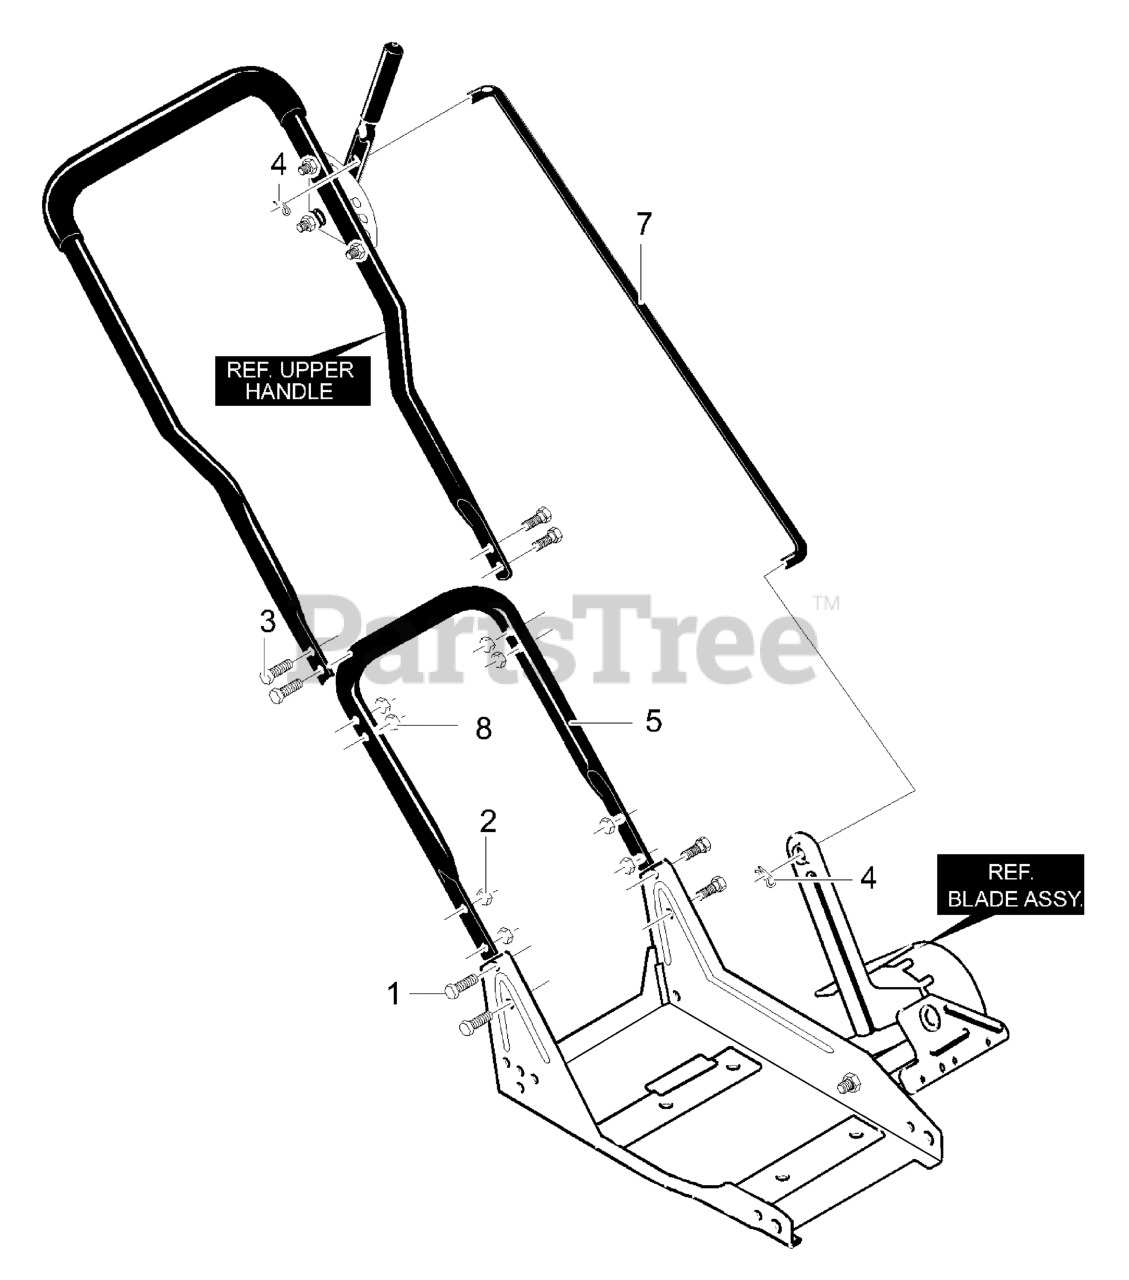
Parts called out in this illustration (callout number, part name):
1	Screw, 5/16-18 x 0.63
2	Nut, 5/16-18
3	Bolt, 5/16-18x1.63
5	Lower Handle
7	Control Rod
8	Nut, 5/16-18
